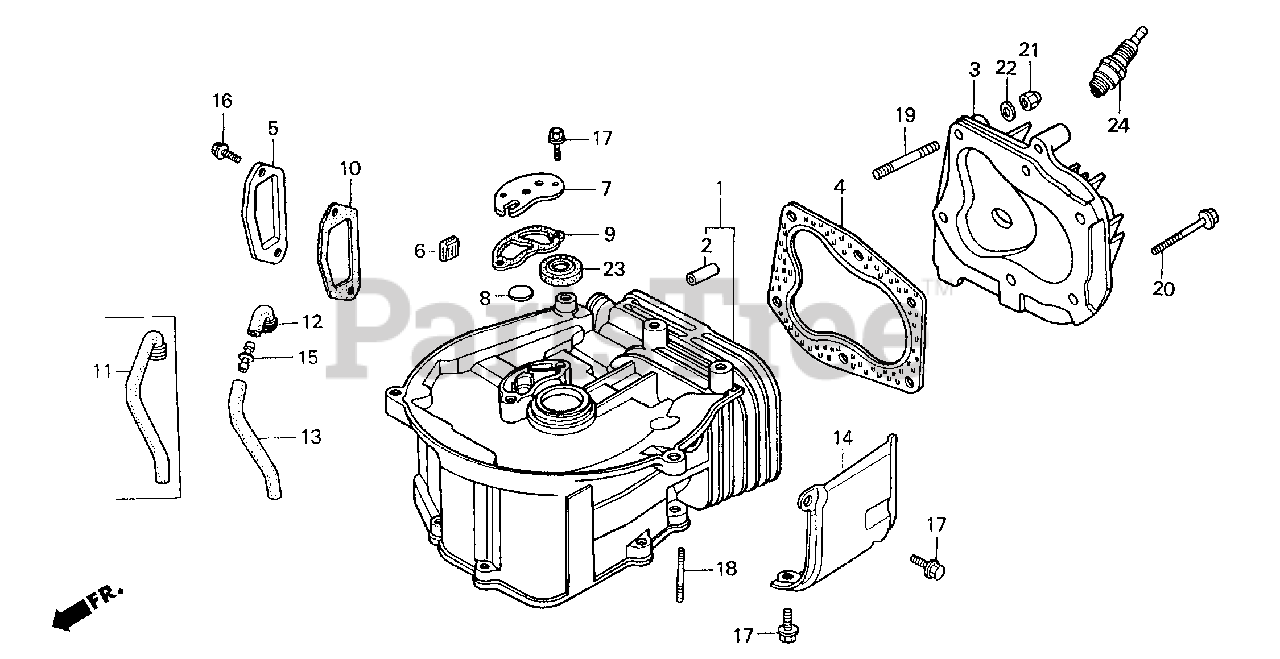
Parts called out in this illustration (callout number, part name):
1	CYLINDER
2	GUIDE, VALVE (OS)
3	CYLINDER HEAD
4	GASKET, CYLINDER HEAD
5	COVER, TAPPET ROOM
6	FILTER, BREATHER
7	CAP, BREATHER CHAMBER
8	VALVE, BREATHER
9	GASKET, BREATHER CAP
10	GASKET, TAPPET COVER
12	TUBE A, BREATHER
13	TUBE B, BREATHER
15	JOINT, OIL TUBE
16	BOLT, FLANGE (5X10)
17	BOLT, FLANGE (6X12)
18	BOLT, STUD (6X24)
19	BOLT, STUD (6X46)
20	BOLT, FLANGE (6X35)
21	NUT, CAP (6MM)
22	WASHER (6MM)
23	OIL SEAL (17X30X6) (NOK)
24	SPARK PLUG (BMR4A) (NGK)
